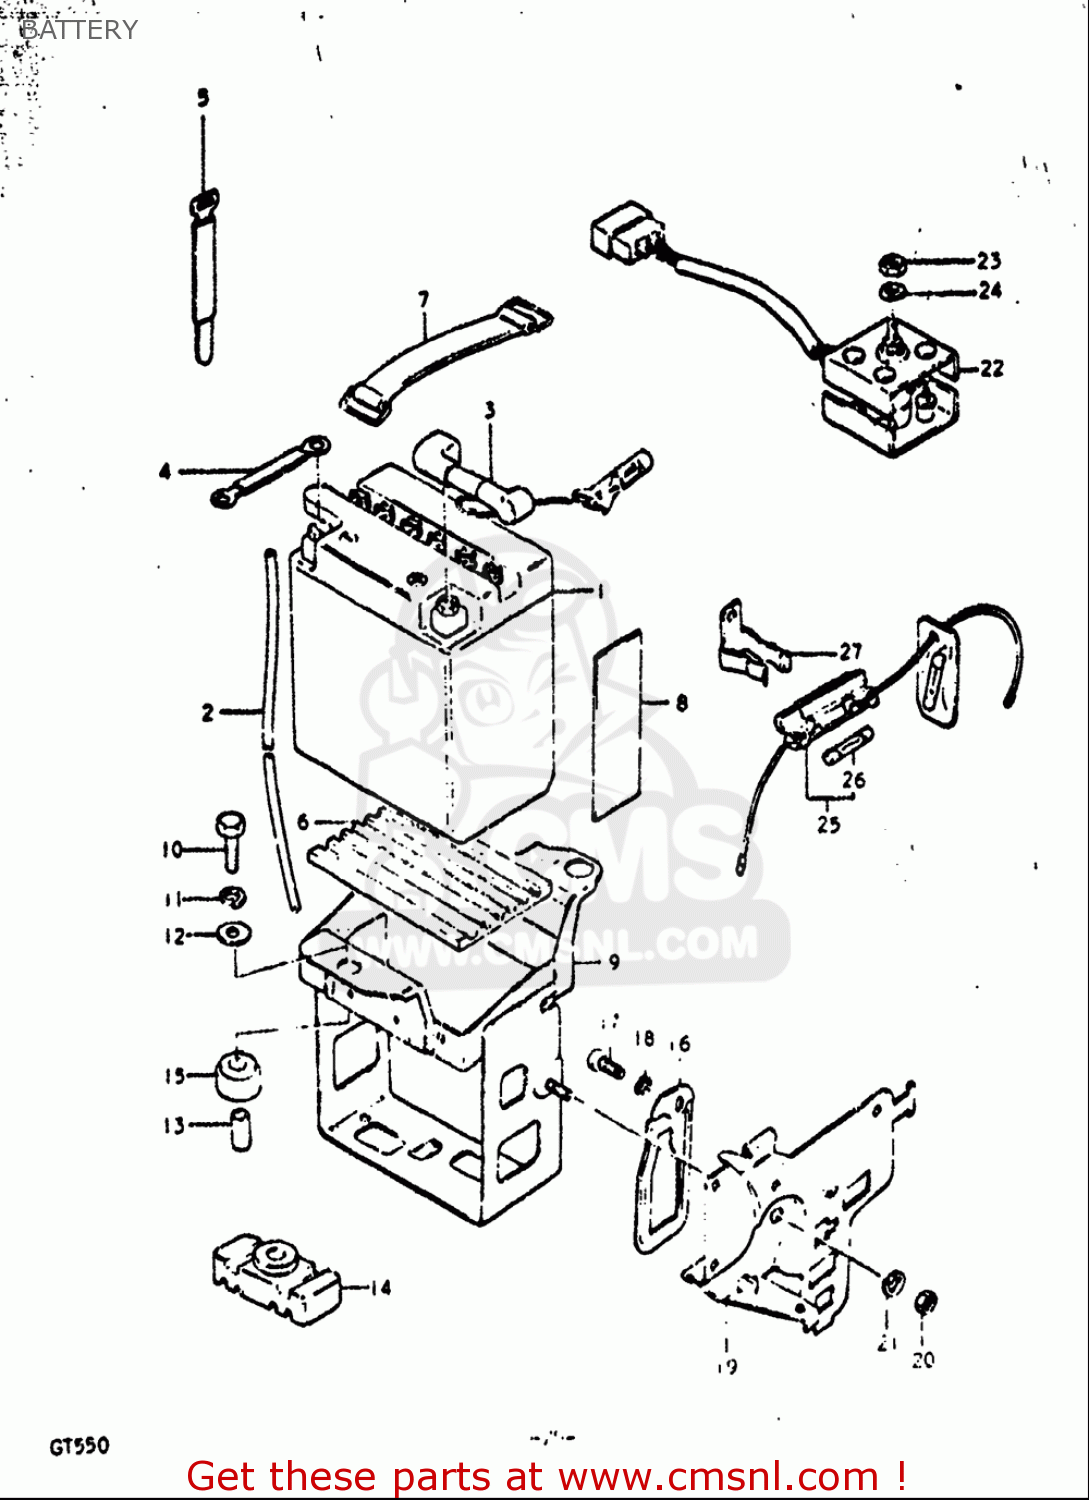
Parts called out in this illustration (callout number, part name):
1	BATTERY ASSEMBLY (12V)
2	HOSE,BATTERY EXHAUST(L:780)
3	LEAD WIRE,BATTERY PLUS
5	CLAMP
6	PROTECTOR,BATTERY
7	BAND
8	PROTECTOR(80X80X2)
10	BOLT
11	WASHER,LOCK
12	WASHER(6.5X18X1.6)
13	SPACER(6.1X8X15.5)
15	CUSHION
17	SCREW
18	WASHER,LOCK
20	NUT
21	WASHER,LOCK
22	RECTIFIER ASSY
23	NUT
24	WASHER,LOCK
25	CASE ASSY,FUSE
26	FUSE(20A)
